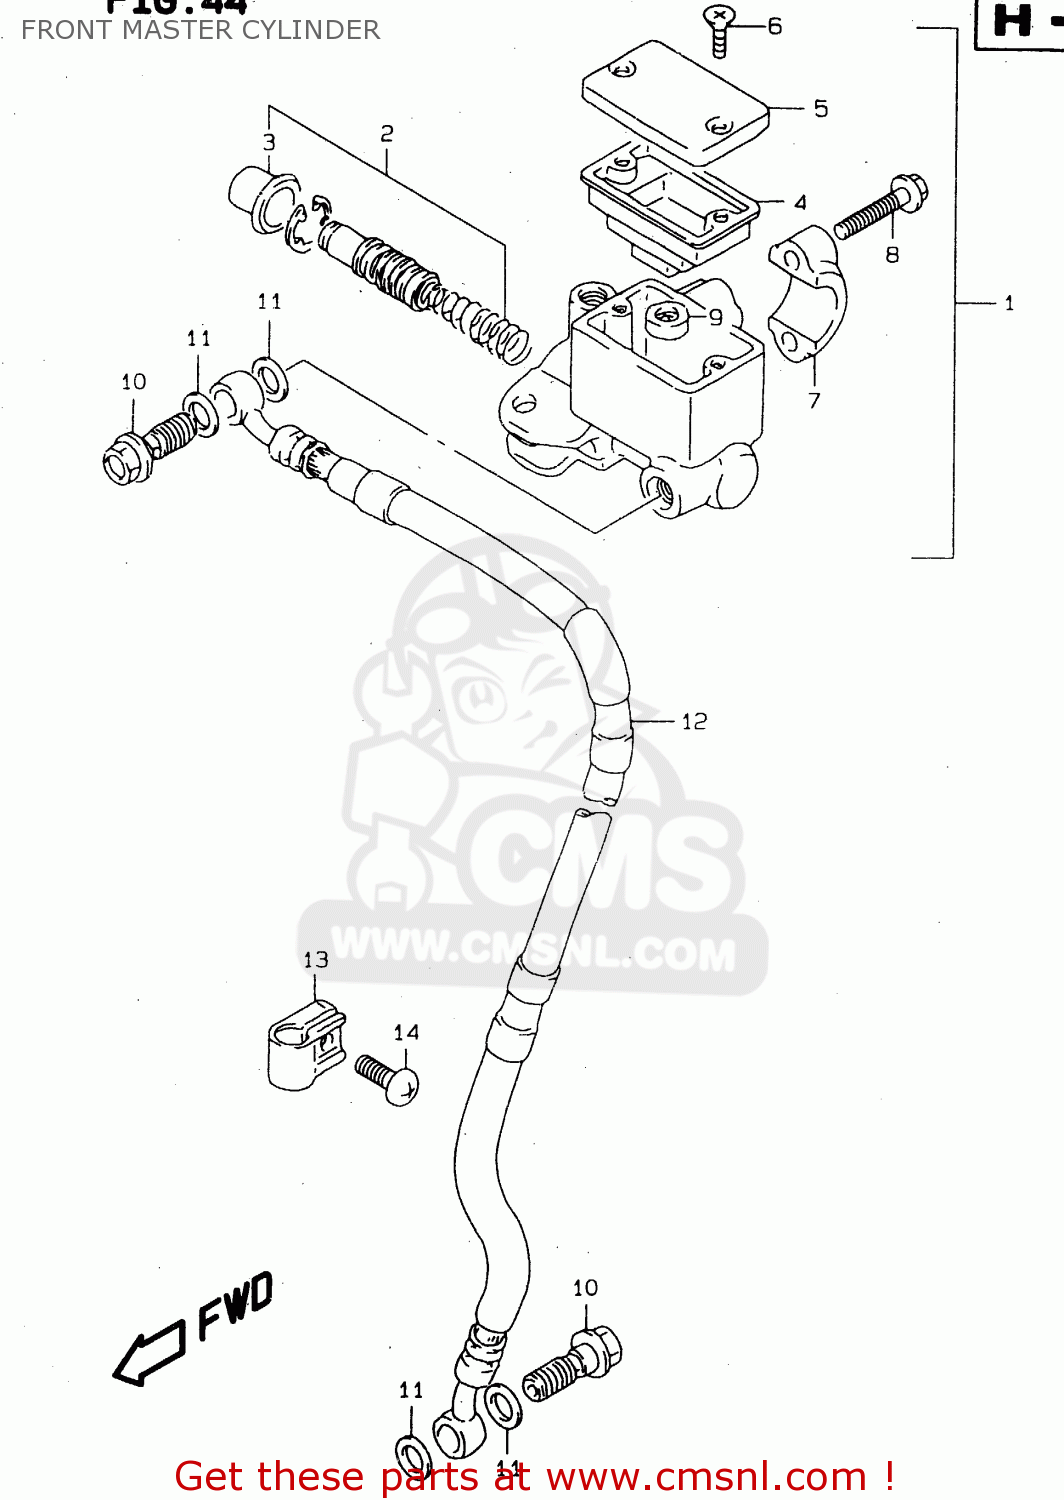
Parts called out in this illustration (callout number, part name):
1	CYLINDER ASSEMBLY,FRONT MASTER
2	PISTON/CUP SET
3	BOOT
4	DIAPHRAGM
5	CAP
6	SCREW
7	HOLDER
8	BOLT
9	SEPARATOR
10	BOLT UNION
11	WASHER(10X15X1.5)
12	HOSE COMP,FRONT BRAKE
13	CLAMP,BRAKE HOSE
14	SCREW
